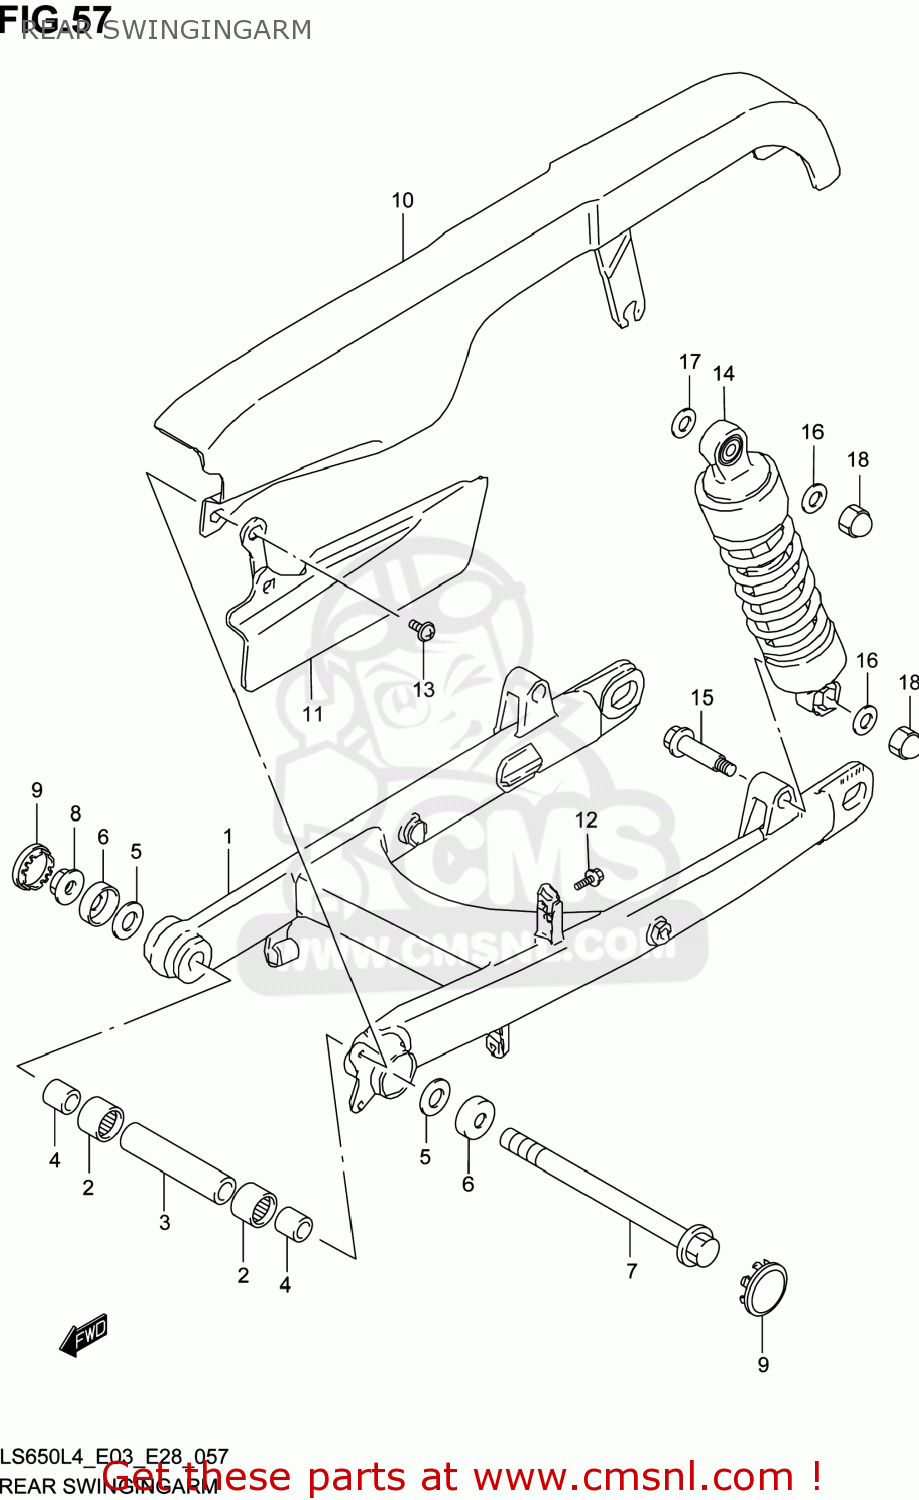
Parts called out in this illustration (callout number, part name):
1	SWINGINGARM,RR
2	BEARING(22X29X30)
3	SPACER,RR SWGARM PIVOT CTR
4	SPACER,RR SWGARM PIVOT
5	WASHER
6	CVR,RR SWGARM DUST SEAL(OD:40)
7	SHAFT,RR SWINGINGARM PIVOT
8	NUT
9	CAP,RR SWINGING ARM PIVOT,R
10	BELT CASE,UPR
11	BELT CASE,LWR
12	BOLT
13	SCREW
14	ABSORBER ASSY,RR SHOCK
15	BOLT,RR SHOCK ABSORBER LWR
16	WASHER(10.5X28X2.3)
17	WASHER(14.5X29X2.3)
18	NUT
